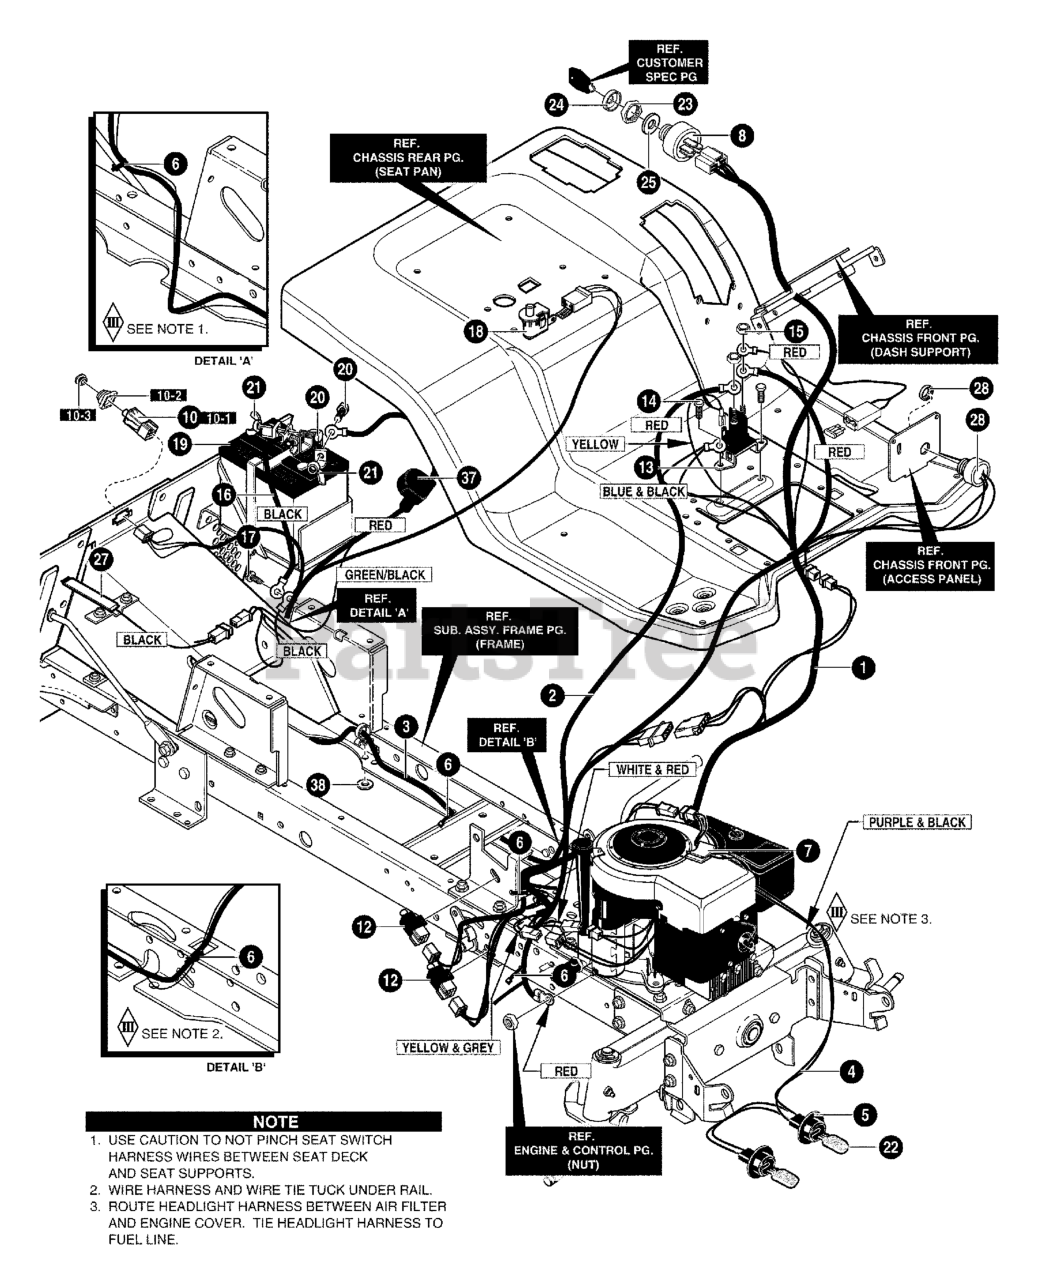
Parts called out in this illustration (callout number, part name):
1	HARNESS, WIRE
2	WIRE, LEAD SOLENOID TO ST
3	REAR HARNESS
4	WIRE HARNESS FOR HEADLIGHTS
5	SOCKET, LAMP
6	TIE, CABLE BLACK
7	WIRE CLIP, ADHESIVE
8	SWITCH, IGNITION
10	SWITCH, DOUBLE POLE DELTA
12	SWITCH LIMIT
13	SOLENOID
14	SCREW,HHWATAP 1/4X.50
15	NUT, 1/4-20 HEXNYL
16	WIRE, GROUND
17	SCREW,HHWATAP 1/4X.50
18	SWITCH, SEAT
19	BATTERY 5 PLATE
20	BOLT,1/4-20X.63 CARR.
21	NUT, WING 1/4-20
22	BULB, LIGHT
23	NUT, 5/8ACME DELTA
24	BOOT, IGN. SWITCH
25	WASHER, REGINTLK
27	TAPE, SWITCH
28	BUZZER, FOR BAG FULL
37	BOOT, BATTERY
38	WASHER, FLAT .250X56X.04
